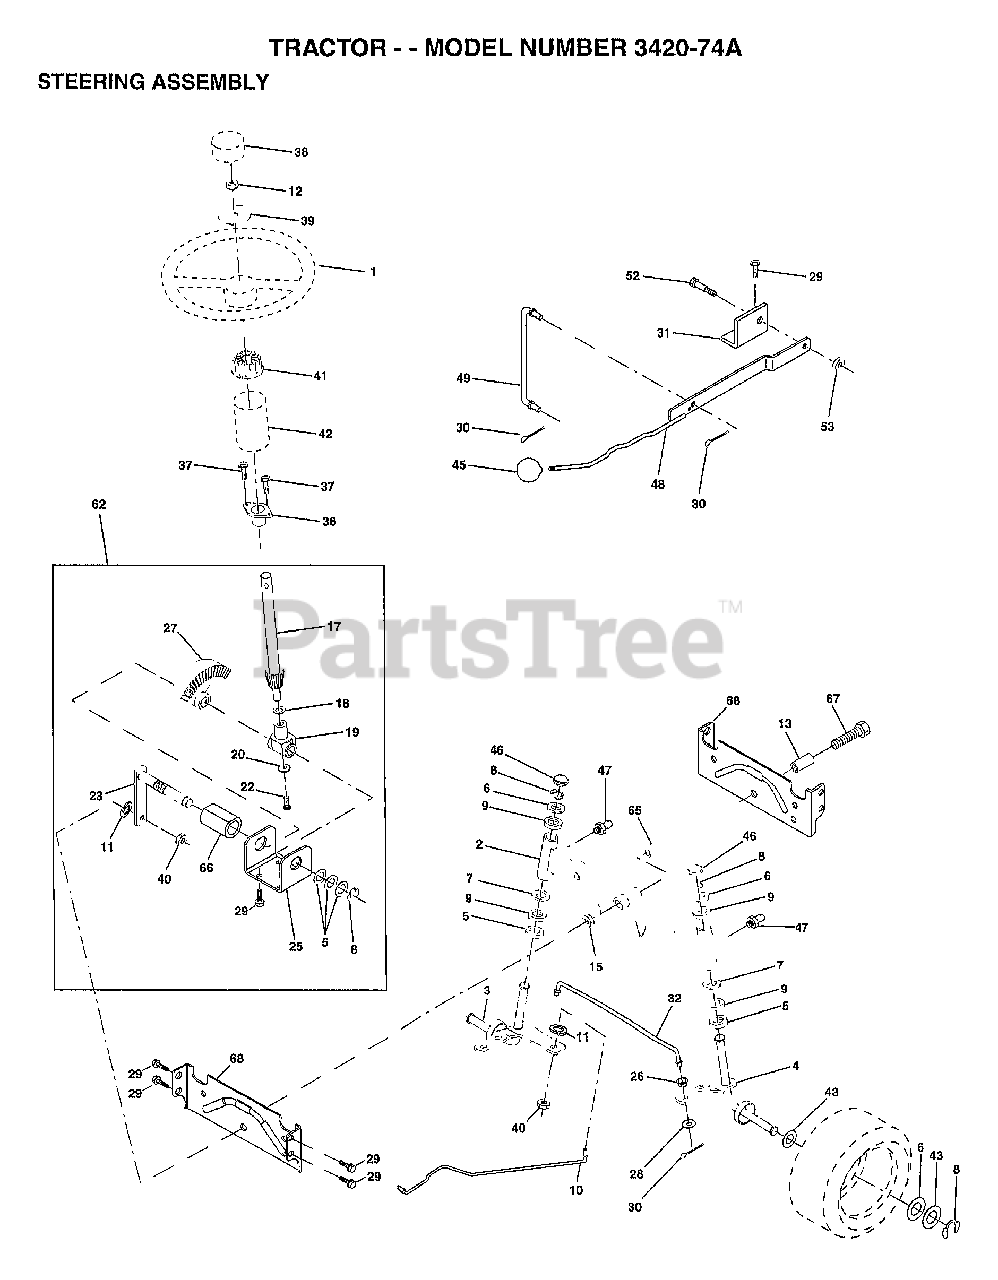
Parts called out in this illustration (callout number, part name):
2	AXLE ASM
3	SPINDLE.ASM.LH
4	"SPINDLE ASM,RH"
5	WASHER .T
6	WASHER
7	WASHER
8	RING
9	COL. SRTG. BEAR.
10	DRAGLINK-STAMPED
11	LOCKWASHER
13	BEARING AXLE
15	"NUT-LOC,FLANGE LT"
17	SHAFT ASM STEERNG
18	THRUST WASHER
19	SUPPORT.SHAFT
22	SCREW HEX SOC1/4-
25	BRKT-STEERING
26	BUSHING.DRAGLINK
27	GEAR SECTOR
28	WASHER
29	SCREW
30	COTTER PIN
32	TIE ROD
36	BUSHING.STRG.3/4
37	"SCREW-TT,10-32 FL"
38	"INSERT,STR WHEEL"
39	WASHER
40	GRIPCO NUT
41	ADAPTER LT
43	WASHER
46	CAP
47	ZERK M
62	KIT STEERING ASM
65	SPACER AXLE
66	"BEARING-ARM,PITMA"
67	BOLT
68	BRACE AXLE
